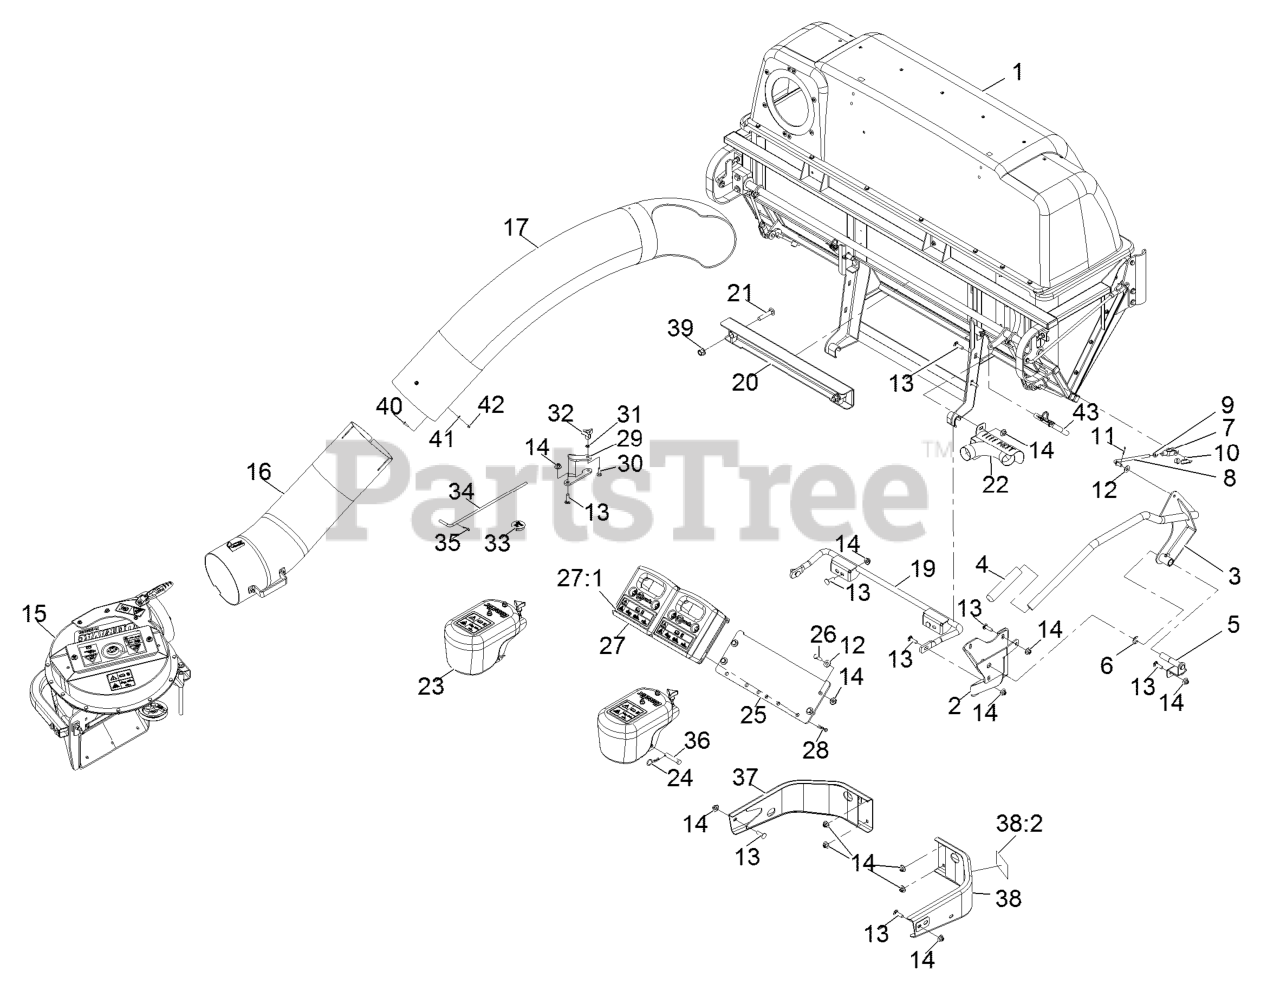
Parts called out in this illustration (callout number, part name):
1	ASM,Hopper Lg Qds
2	MOUNT-PIVOT
3	WLD,DUMP HANDLE
4	HANDLE-GRIP
5	PIN-HANDLE
7	YOKE-LINKAGE, BRAKE
8	LINK-HANDLE
9	NUT-HEX
10	PIN-SPRING, CLEVIS
11	PIN-COTTER
12	WASHER-FLAT
13	Bolt-Carriage 3/8-16 X 1 1/4
14	Nut-Nyloc 3/8-16 Flg
15	ASM, BLOWER LARGE - SVC O
16	LOWER TUBE ASM
17	TUBE-UPPER
19	MOUNT-BAGGER, LOWER
20	MOUNT-BAGGER, UPPER
21	SCREW-CARR
22	EXHAUST DIVERTER ASM
23	ASM,CASTER WEIGHT
24	PIN-COTTER
25	PLATE,WEIGHT ASM MOUNT
26	SCREW-HH
27	ASM,CAST WEIGHT
27:1	DECAL-WARNING WEIGHT
28	PIN-HAIR
29	BRACKET,BELT COVER
30	BOLT-CARR
31	RING-RETAINING, BOLT
32	KNOB-3 PRONG
33	PLUG, BLACK NYLON 1.75
34	PIN,CHUTE PIVOT
35	PIN-COTTER
36	PIN-CLEVIS
37	BUMPER-RH
38	LH BUMPER ASM
38:2	DECAL-WARNING
39	Nut-Lock 1/2-13
40	SCREW-HWH
41	WASHER-FLAT
42	NUT-LOCK, NI
43	PIN-MOUNT, BAGGER
